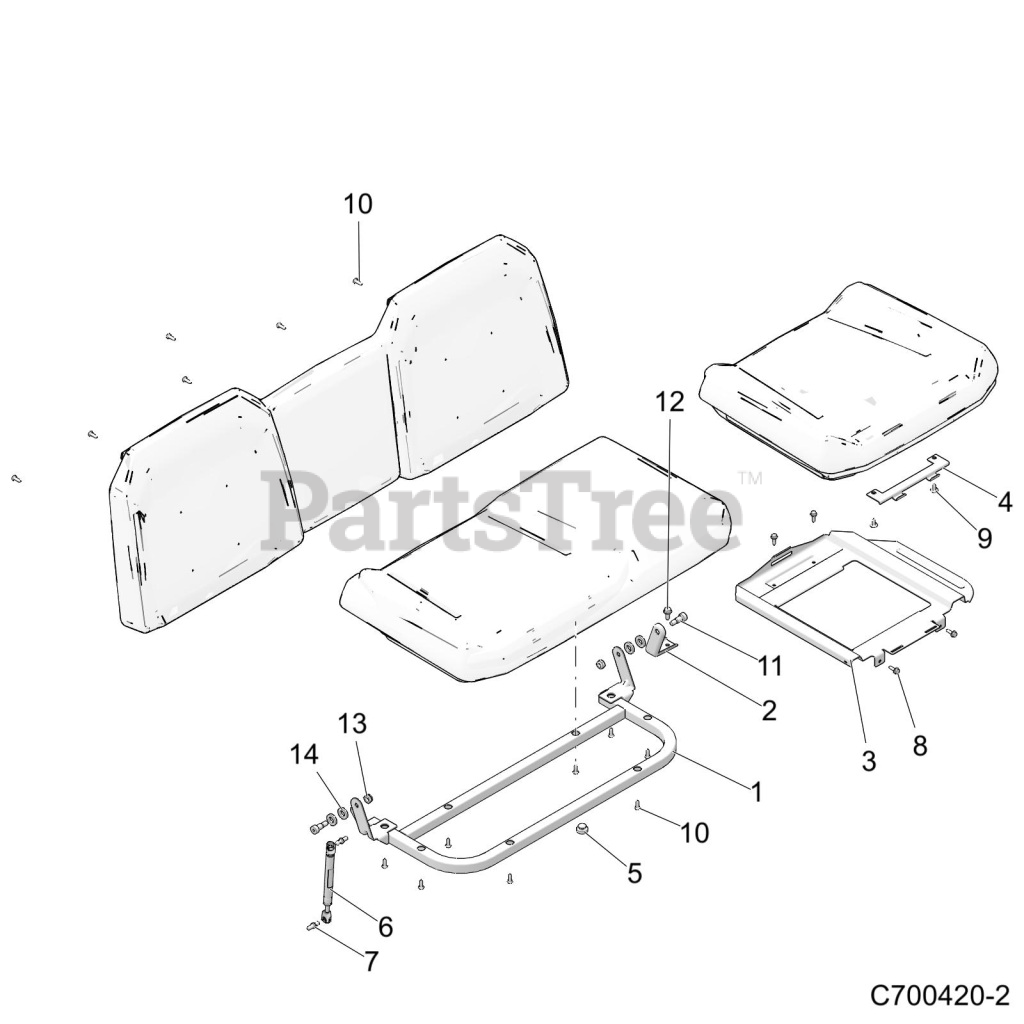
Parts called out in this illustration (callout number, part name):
1	WELD-SEAT BASE,PASS,M.BLK
2	BRKT-SEAT PIVOT,BLK
3	BRKT-SEAT SUPPORT,FIXED,BLK
4	BRKT-SEAT PIVOT,FIXED,BLK
5	BUMPER-RUBBER
6	SHOCK-GAS,285MM
7	BALL-END
8	SCR-M6X1.0X20,HXHD,FLG,TDFM,BL
9	SCR-M6X1X16 TR/TX-M
10	SCR-TX TRUSS-#14X3/4,HI/LO ZBK
11	SCR-SHS-M10X1.5-M12X16 RIE
12	SCR-HWH-M8X1.25X20 TAP/R ZPB
13	NUT-HEX M10X1.5 8 ZOD NYL
14	WASHER-SEATBELT,RUBBER
